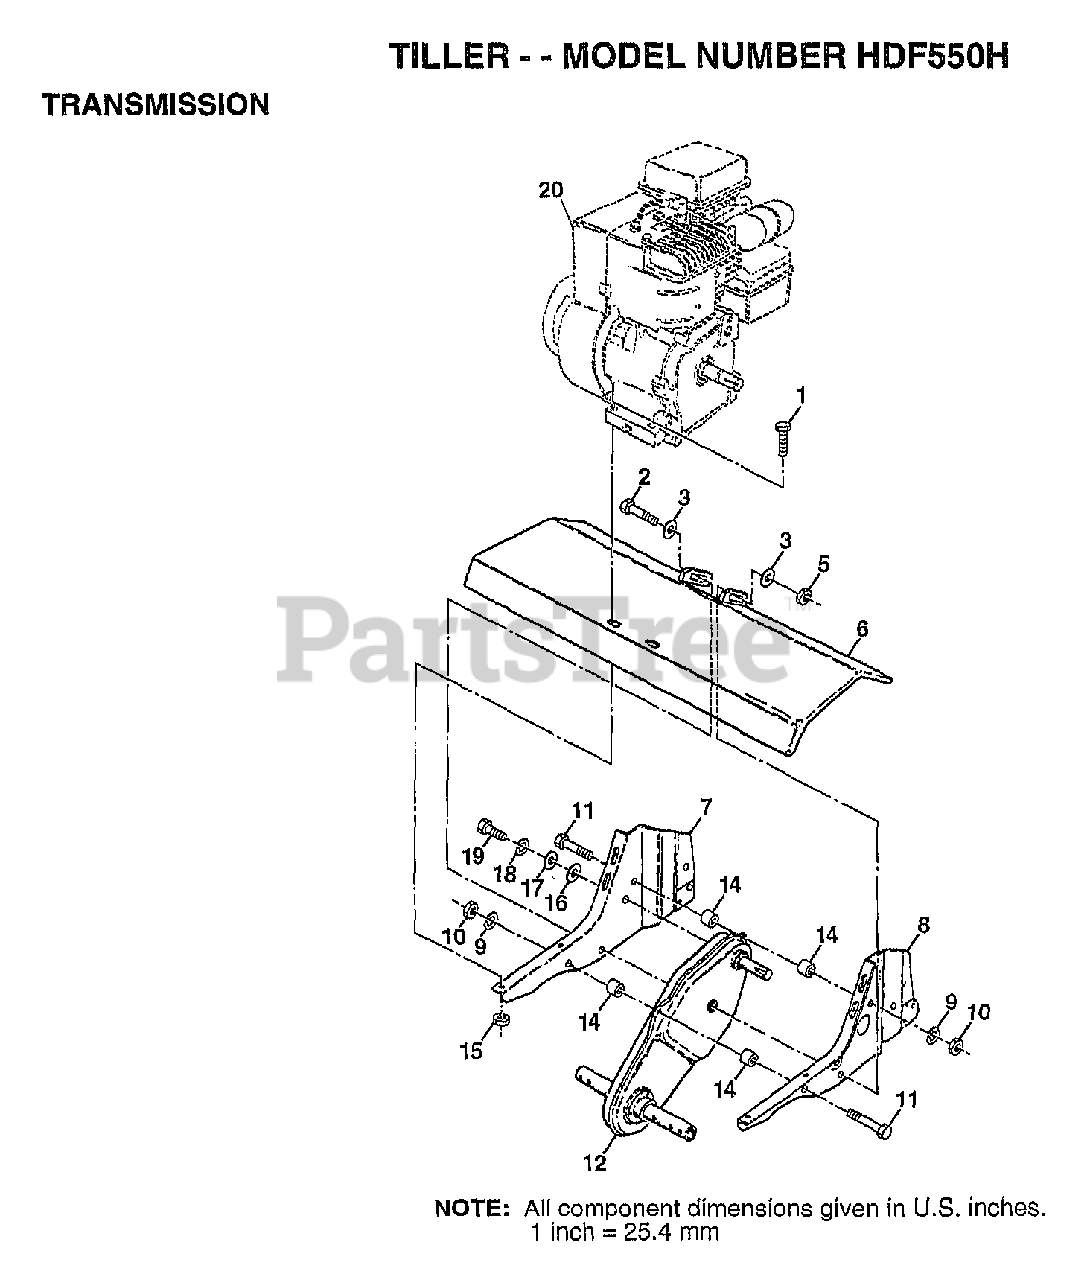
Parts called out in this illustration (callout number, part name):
1	BOLT.HEX.5/16-1.5
2	BOLT HEX 3/8-16
3	WASHER
5	NUT
6	SHIELD TINE
7	BRACKET.ENGINE.RH
8	ENGINE BRKT LH TI
9	LOCKWASHER
10	NUT.HEX.5/16-18
14	SPLIT SPACER RT
16	WASHER
17	WASHER
18	LOCKWASHER
19	BOLT
